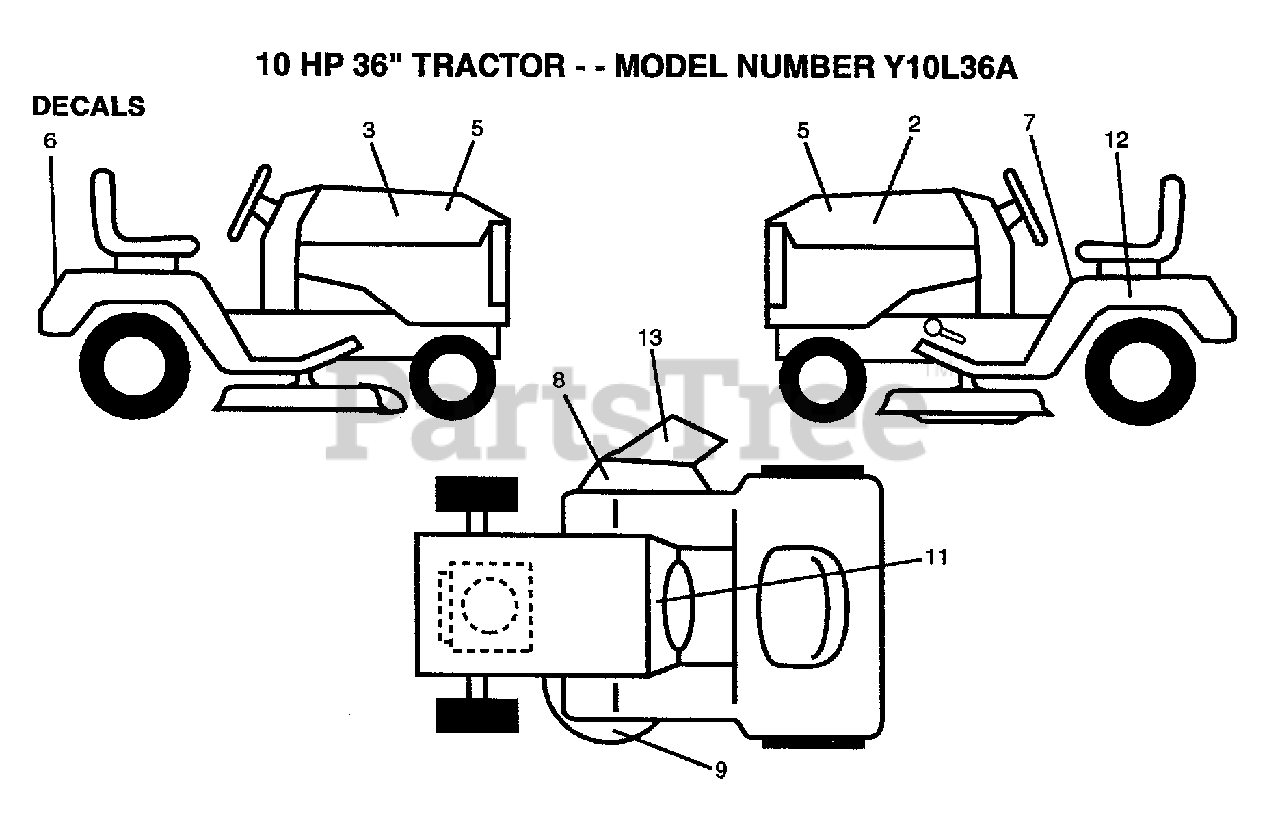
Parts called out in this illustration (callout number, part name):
7	DECAL CAUTION
8	DECAL WARNING
9	DECAL YT
12	DECAL
13	DECAL WARNING
